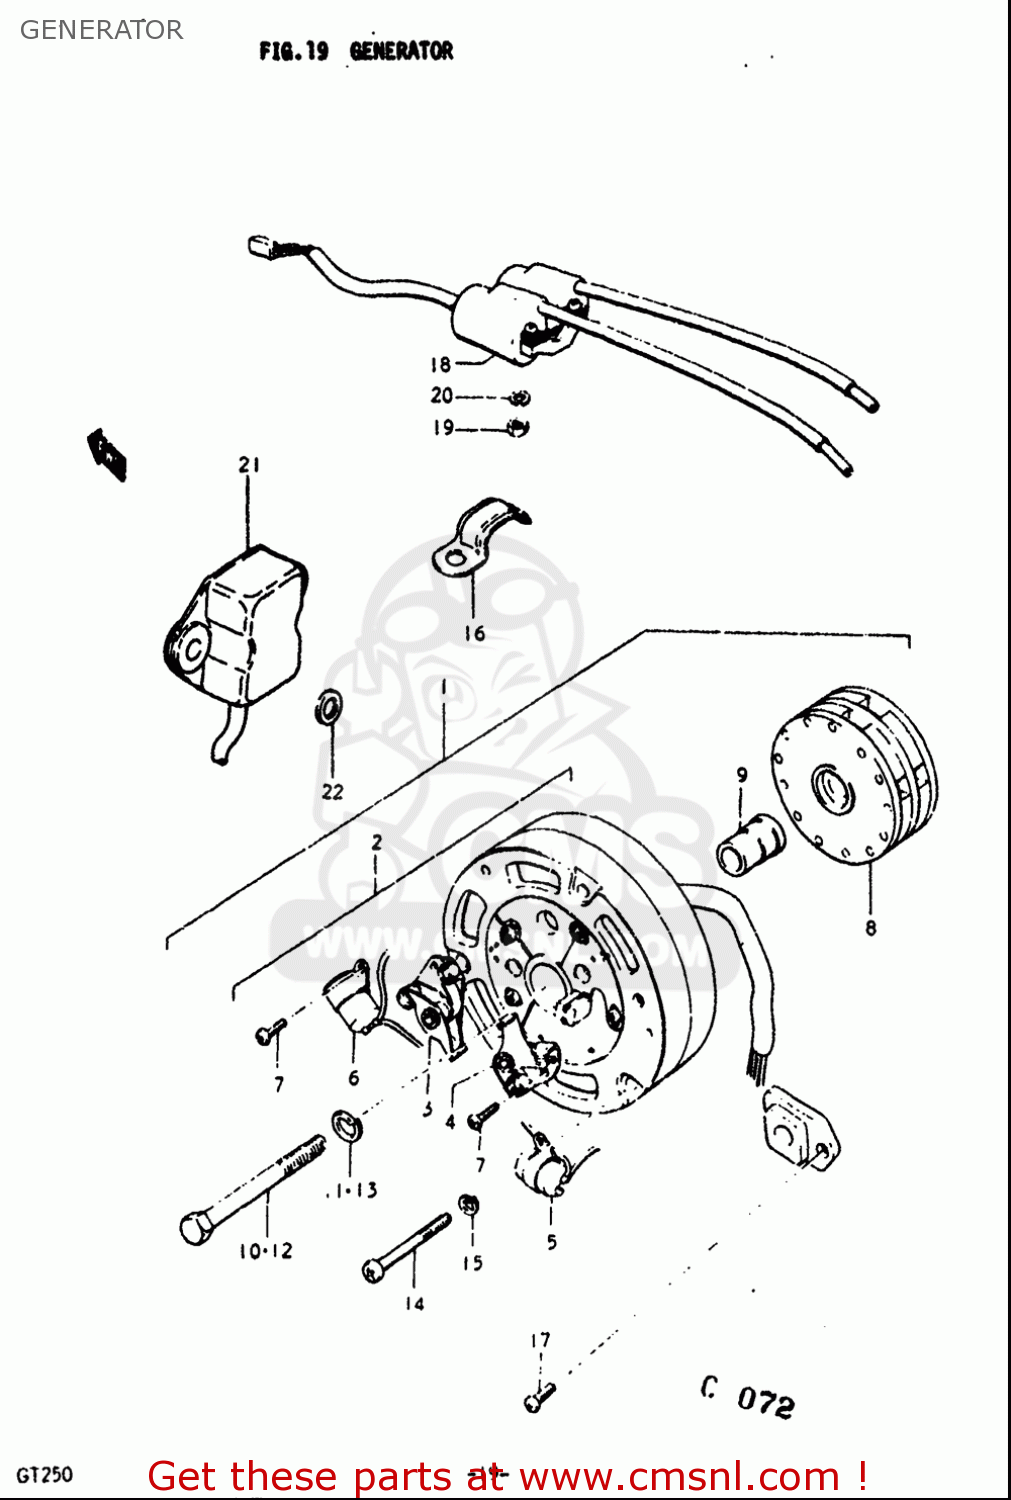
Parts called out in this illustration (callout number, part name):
3	POINT ASSY,CONTACT
4	POINT,CTR
5	CONDENSER,R
6	CONDENSER,L
7	SCREW 4X6
11	WASHER,LOCK
12	BOLT
13	WASHER,LOCK
14	SCREW
15	WASHER,LOCK
16	CLAMP
17	SCREW
18	COIL ASSY,IGNITION
19	NUT
20	WASHER,LOCK
22	WASHER
